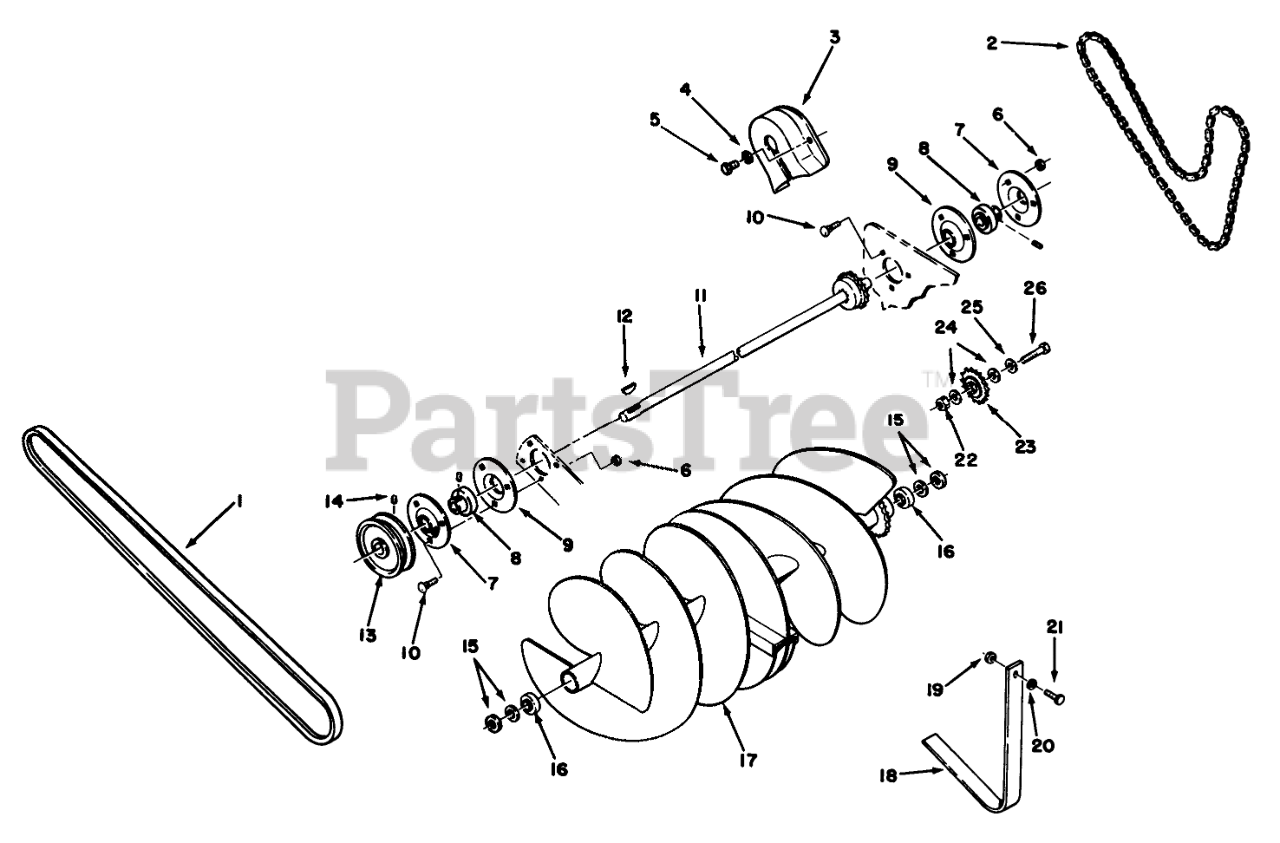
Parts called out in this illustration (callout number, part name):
1	Belt
2	CHAIN-64 PITCHES
3	GUARD-CHAIN
4	Washer
5	SCREW-HWH
6	NUT-LOCK, NI
7	FLANGE-ZERK RELUBE
8	BEARING AND COLLAR
9	Flange
10	BOLT-CARR
11	Shaft Assembly
12	Key-Woodruff
13	PULLEY
14	SCREW-SQH
15	WASHER-FLAT
16	BEARING-BALL
17	Auger
18	Guard-Outer
19	NUT-KEPS
20	WASHER-FLAT
21	SCREW-HH
22	NUT-LOCK, NI
23	Idler Sprocket
24	WASHER-FLAT
25	SPACER
26	SCREW-HH
